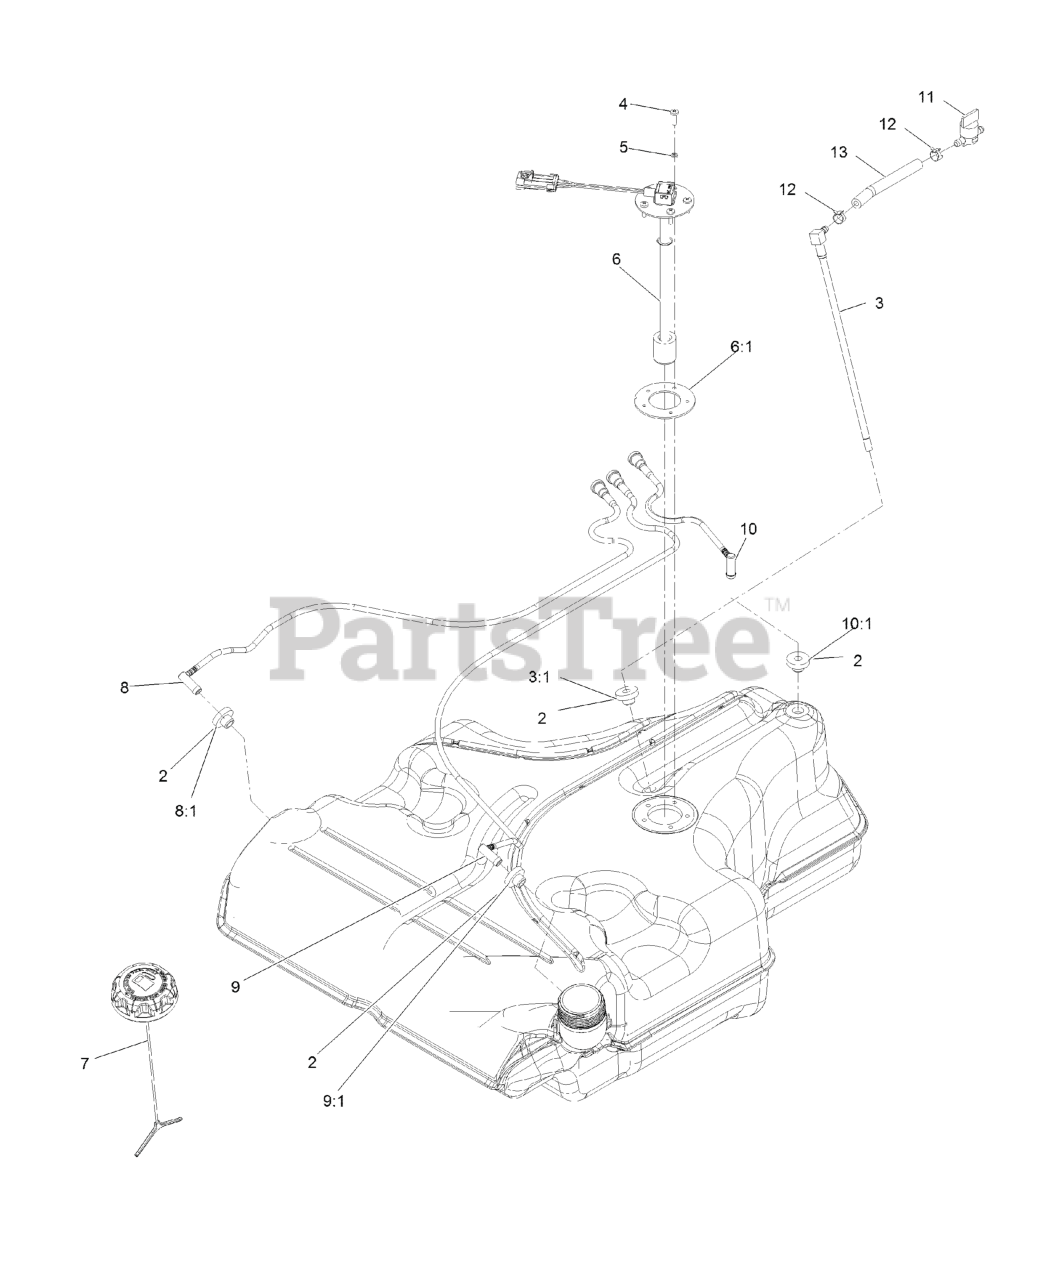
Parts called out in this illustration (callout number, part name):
2	BUSHING
3	FUEL LINE KIT (WITH GROMMET)
3:1	BUSHING
4	SCREW-PPH
5	WASHER-LOCK
6	SENDER-LEVEL, FUEL (W/GAS
6:1	Gasket-Sender
7	CAP-FUEL, RATCHETING
8	RH VENT LINE KIT (WITH GROMMET)
8:1	BUSHING
9	LH VENT LINE KIT (WITH GROMMET)
9:1	BUSHING
10	REAR VENT LINE KIT (WITH GROMMET)
10:1	BUSHING
11	VALVE-FUEL
12	CLAMP-HOSE
13	HOSE-FUEL
